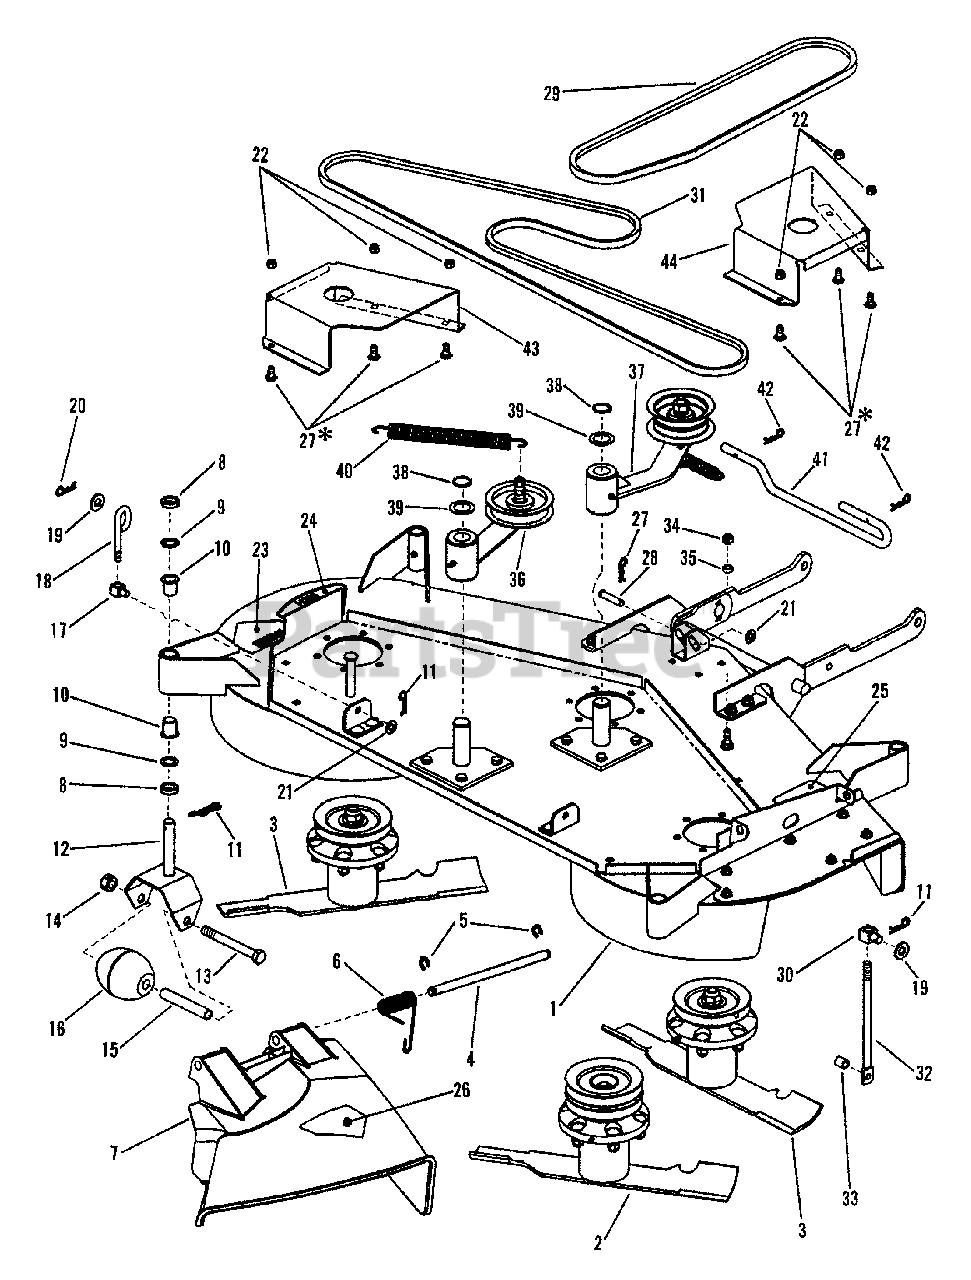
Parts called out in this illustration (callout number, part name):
1	ASSEMBLY, 48" Deck
2	* ASSEMBLY, Drive Spindle
3	* ASSEMBLY, L.H./R.H.Spindle
4	PIN, Chute Hinge
5	RING, Retaining
6	SPRING, Torsion (Side Chute)
7	CHUTE, Side Discharge
8	WASHER, Spacer
9	WASHER, 3/8" Flat
10	BEARING, 1/2 x 3/4" Plastic
11	PIN, 3/32 x 1-1/2" Hair
12	WELDMENT, Anti-Scalp Wheel
13	SCREW, 1/2-20 x 4-1/2" Hex Head Cap, Grade 5
14	NUT, 1/2-20 Hex Center Lock, Grade 5
15	SLEEVE, Caster Wheel
16	ROLLER, Low Density Polyethylene
17	SWIVEL, Brake Link
18	ROD, Rear Lift
19	WASHER, 1/2" Flat
20	PIN, 1/2" Self-Locking Cotter
21	WASHER, 3/8" Flat
22	NUT, 5/16-18 Hex Nyloc
23	DECAL, Warning - CPSC "Cut Finger"
24	DECAL, 48" Deck
25	DECAL, Chute/Deflector Warning
26	DECAL, CPSC Heavy Adhesive
27	BOLT, 5/16-18 x 3/4" Short Neck Carriage, Grade 5
28	PIN. 3/8 x 1-1/2" Clevis
29	BELT, 50.65 HA (Electric Clutch)
30	SWIVEL, Lift
31	BELT, 94.46 HA
32	ROD, Front Lift
33	SPACER, Axle
34	NUT, 3/8-16 Hex Center Lock
35	SPACER, Tie Rod
36	** ASSEMBLY, Deck Idler
37	** ASSEMBLY, Drive Idler Arm
38	RING, 1" External Retaining
39	BUSHING, 1" Machine
40	SPRING, Extension- Primary Idler
41	PIN, Deck Hanger
42	PIN, 3/32 x 1-1/2" Hair
43	COVER, L.H. Spindle
44	COVER, R.H. Spindle
